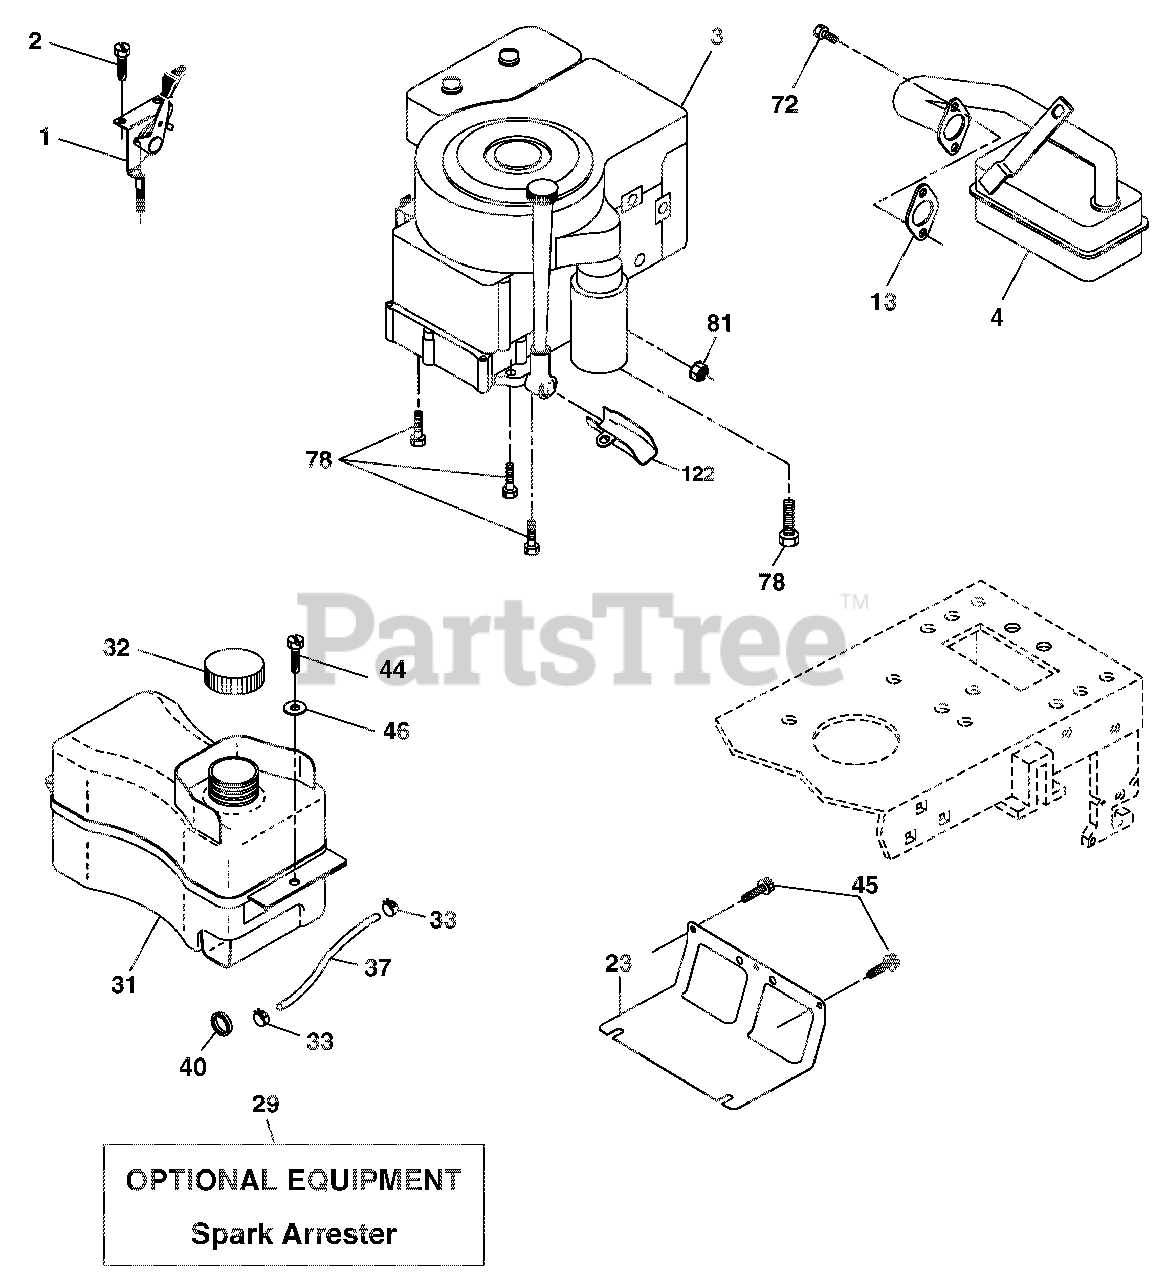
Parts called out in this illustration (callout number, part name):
1	Control Th/ch Flag
2	Screw 1/4-20 x 1/2
4	Muffler Exhaust B&S
23	Shield BRN/DBR Guard
29	KIT.SPARK ARRESTOR(392390 B&S)
31	TANK.FUEL.FRT.N/CAP.1.5GAL.DAP
32	Cap Fuel
33	CLAMP.HOSE.BLK.
37	LINE.FUEL.22"FRONT.EMIS.CA.LP
40	Bushing Snap Nyl Blk Fuel Line
44	SCREW.HEXWSH.THDROL.1/4-20X3/4
45	SCREW.HEXWSH THDR3/8-16X3/4.BL
46	WASHER.9/32 X 7/8 X 16GA.
72	SCREW.SOCKET HD.5/16-18 X .75
78	Screw 3/8-16 x 1-1/4
81	Nut, Keps Hex 1/4-20 unc
122	Extension Drain Oil
